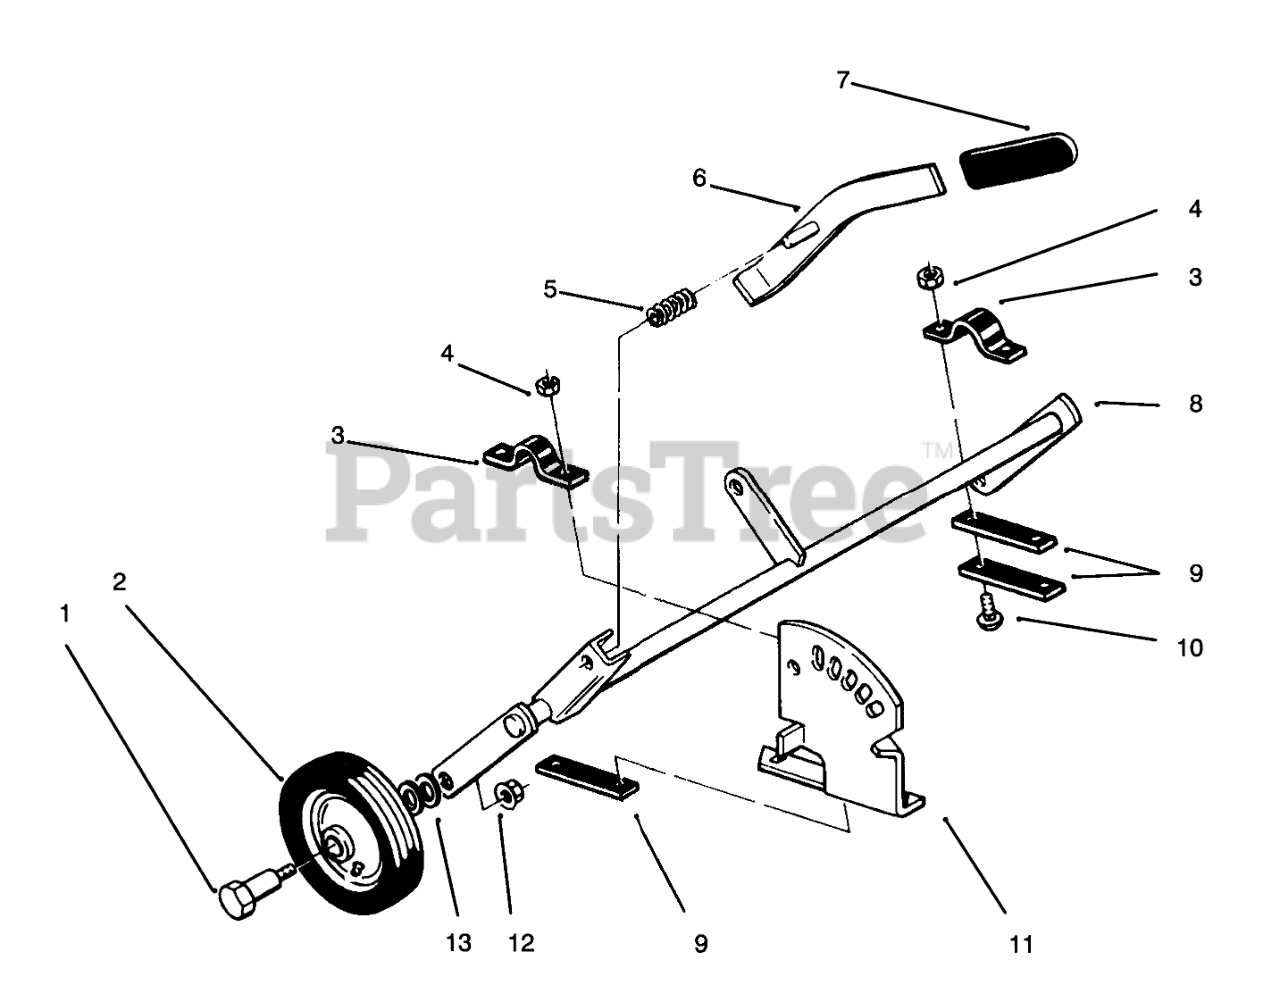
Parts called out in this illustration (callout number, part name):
1	BOLT-SHOULDER
2	WHEEL ASM
4	NUT-HEX
5	SPRING-COMPRESSION
6	Lever
8	Gage Wheel Support
9	Bar
10	BOLT-CARR
11	Quadrant
12	NUT-HEX
13	WASHER-LOCK/EXT
